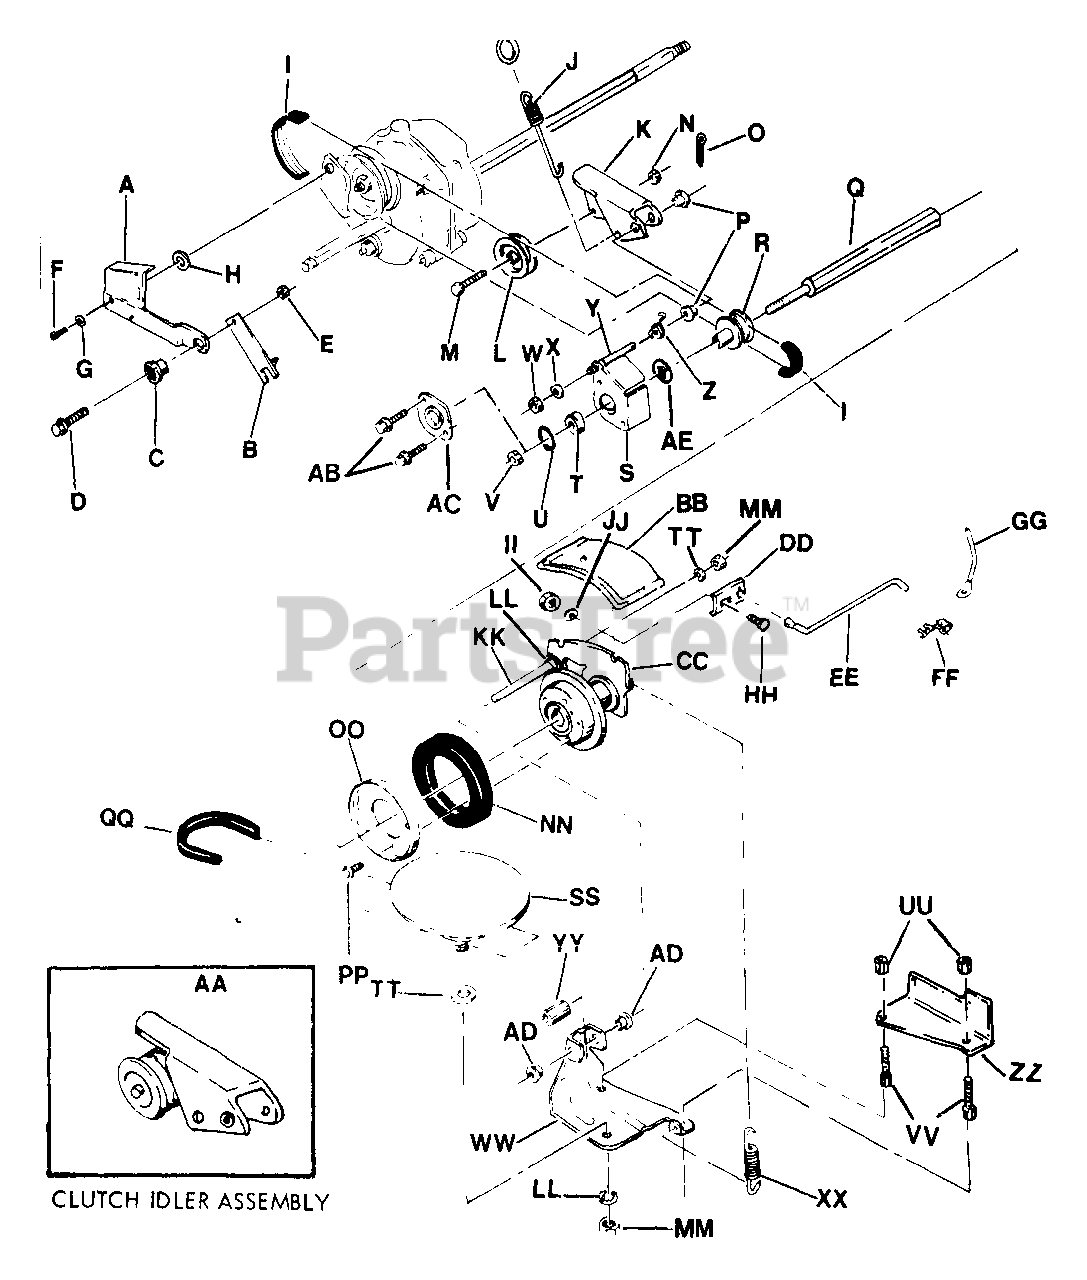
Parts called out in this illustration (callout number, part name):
A	LINK, Differential
B	GUIDE, LOWER BELT
C	BUSHING, DIFFERENTIAL LINK
D	CAPSCREW, HEX HEAD 5/16-24 x 1 (21500PC)
D	CAP SCREW, HEX HEAD 5/16-24 x 1 1/4 (21350P & 21400P)
E	NUT, HEX LOCK 5/16-24
F	CAPSCREW, HEX HEAD 5/16-18 x 3/8
G	WASHER, INTERNAL TOOTH LOCK 5/16
H	WASHER, SPRING
I	BELT, POLY V
J	SPRING, CLUTCH
K	ARM, CLUTCH IDLER
L	PULLEY, IDLER
M	CAPSCREW, HEX HEAD 1/4-28 x 1 3/8
N	NUT, HEX LOCK 1/4-24
O	PIN, COTTER 3/32 x 3/4
P	BUSHING, 3/8 I.D. NYLON
Q	SHAFT, Hex
R	PULLEY, POLY V-BELT
S	HOLDER, BEARING (HALF)
T	BEARING, HEX SHAFT BALL
U	O-RING
V	NUT, LOCK 3/8-24
W	NUT, HEX 3/8-24
X	WASHER, INTERNAL TOOTH LOCK 3/8
Y	STUD, IDLER
Z	SPRING, IDLER TORSION
AA	IDLER, CLUTCH ASSEMBLY
BB	COVER, DRIVEN RING
CC	ASSEMBLY, Driven Disc
DD	CONNECTOR, TRANSFER ROD
EE	ROD, TRANSFER
FF	CLIP, TRANSFER ROD RIGHT ARC 1/4"
GG	LEVER, SPEED CONTROL
HH	BOLT, CARRIAGE 5/16-18 x 3/4
II	NUT, HEX 5/16-18
JJ	WASHER, LOCK 5/16
KK	GUIDE, THRUST PLATE
LL	WASHER, INTERNAL TOOTH LOCK 3/8
MM	NUT, HEX 3/8-24
NN	RING, Driven (Rubber Disc)
OO	PLATE, DRIVEN RING
PP	SCREW, #10-24 x 1/2" Hex Washer Self-Tap (Torx)
QQ	BELT, ENGINE 21350P & 21400P
QQ	BELT, ENGINE 21500PC
SS	DISC, DRIVE ASSEMBLY
TT	WASHER, FLAT 3/8 SAE
UU	NUT, 5/16C FLANGE
VV	BOLT, CARRIAGE 5/16C x 1/2 (SHORT NECK)
WW	BRACKET, Deck
XX	SPRING, WHEEL DRIVE
YY	SPACER, DECK BRACKET
ZZ	BRACKET, STRAP 21500PC
AB	SCREW, SELF-TAPPING 1/4-20 x 3/8
AC	HOLDER, BEARING (OUTER HALF)
AD	BUSHING, FLANGE
AE	WASHER, SPACER
